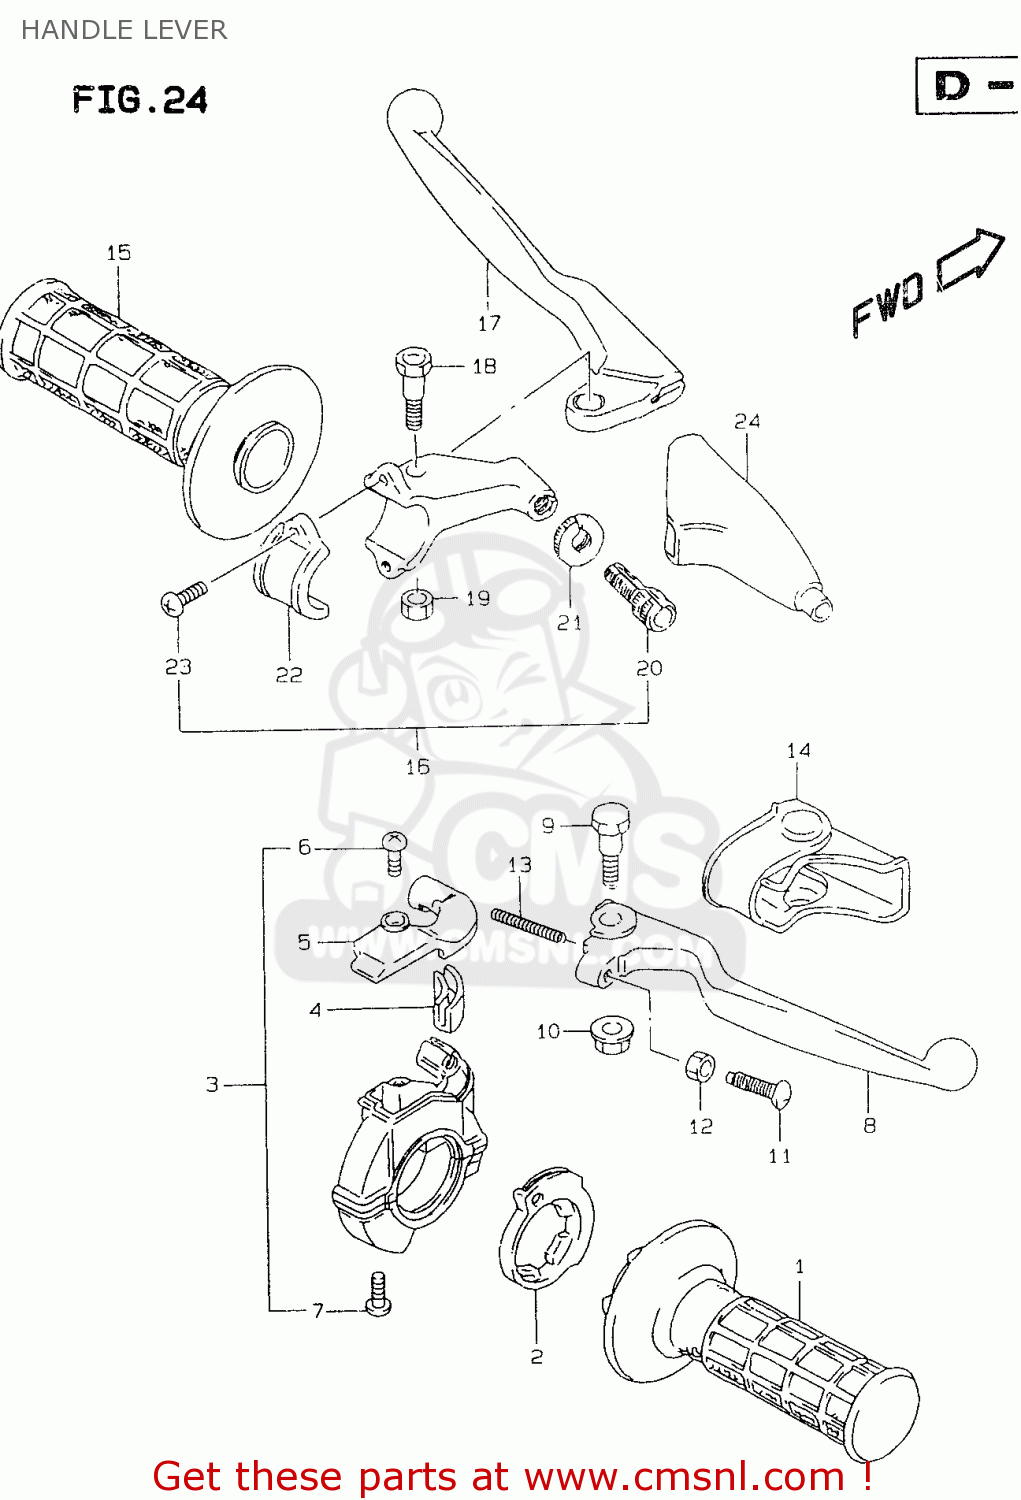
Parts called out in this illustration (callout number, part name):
1	GRIP,THROTTLE
2	ROTOR,THROTTLE GRIP
3	CASE ASSY,THROTTLE
4	GUIDE PIECE,THROTTLE
5	COVER,THROTTLE CASE
6	SCREW,UPPER
7	SCREW
8	LEVER,BRAKE
9	BOLT,BRAKE LEVER
10	NUT,BRAKE LEVER
11	BOLT,ADJUST
12	NUT
13	SPRING,RETURN
14	COVER,BRAKE LEVER
15	GRIP,L
16	LEVER ASSY,CLUTCH
17	LEVER,CLUTCH
18	BOLT,LEVER
19	NUT 6MM
20	ADJUSTER,CABLE
21	NUT,CABLE ADJUSTER
22	BRACKET,CLUTCH LEVER HOLDER
23	SCREW(5X14)
24	COVER,CLUTCH LEVER
